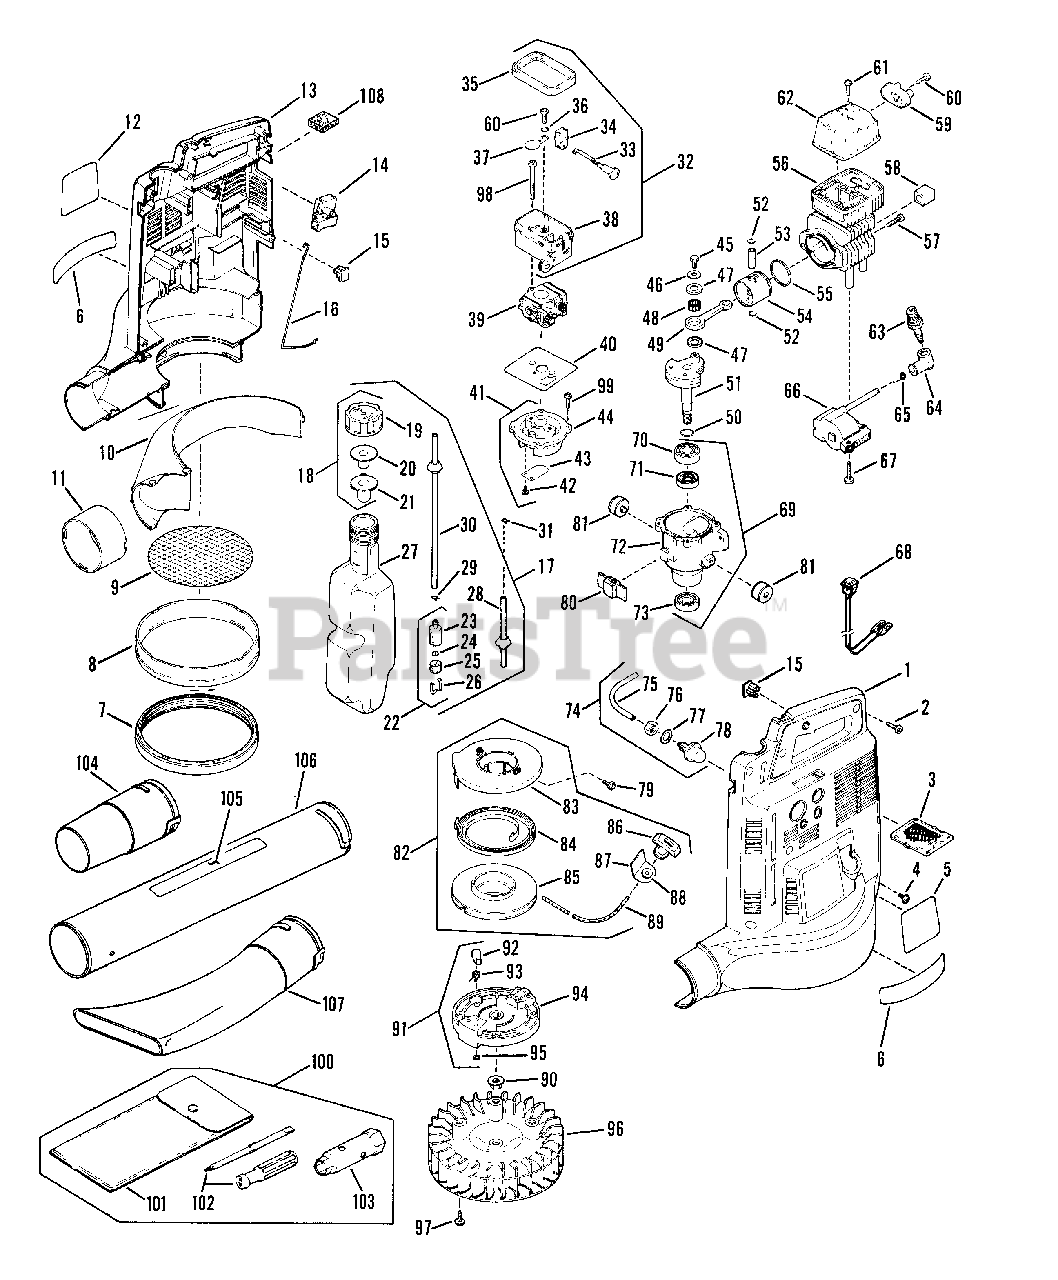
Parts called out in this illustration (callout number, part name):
1	HOUSING, Blower (L.H.)
2	SCREW, M4.5x 18mm
3	ELEMENT, Air Filter
4	SCREW, M4 x 16mm
5	DECAL, Starting Instructions
6	DECAL, Snapper
7	RING, Lower Housing
8	RING, Air Inlet
9	GUARD, Mesh
10	GUIDE, Air Flow
11	RING, Exhaust
12	DECAL, Model
13	HOUSING, Blower (R.H.)
14	ASSEMBLY, Throttle/Lockout
16	ROD, Throttle
17	ASSEMBLY, Tank
18	ASSEMBLY, Cap
19	CAP, Fuel Tank
22	ASSEMBLY, Filter
26	RETAINER
27	TANK, Fuel
28	TUBING, Overflow
30	TUBING, Filter
32	ASSEMBLY, Body
33	ROD, Choke
34	GROMMET
38	BODY
39	ASSEMBLY, Carburetor (See page 4 for breakdown)
41	ASSEMBLY, Cover
44	COVER
48	BEARING, Roller
49	ROD, Piston
51	ASSEMBLY, Crankshaft
52	RING, Clip
53	PIN, Piston
54	PISTON
55	RING, Piston
56	CYLINDER
57	SCREW, M5 x 20mm
58	MOUNT, Rear
59	TAIL, Muffler
60	SCREW, M4 x 16mm
61	SCREW, M5 x 2mm
62	MUFFLER
64	CAP, Spark Plug
66	ASSEMBLY, Coil
67	SCREW, M4x25mm
68	ASSEMBLY, Switch
69	ASSEMBLY, Crankcase
70	BEARING
72	HOUSING, Crankcase
73	BEARING
74	ASSEMBLY, Pump
75	HOSE, Primer Joint
76	NUT, Primer
78	ASSEMBLY, Primer Body
79	SCREW, M4x8mm
80	MOUNT, Front
81	MOUNT, Side
82	ASSEMBLY, Starter
83	PLATE, Starter
86	HANDLE, Rope
88	GUIDE, Rope
89	ROPE, Starter
91	ASSEMBLY, Rotor
92	RATCHET
97	SCREW, M4x20mm
98	SCREW, M5x45mm
99	SCREW, M4x16mm
100	KIT, Tool
101	BAG
102	SCREWDRIVER
103	SOCKET
104	NOZZLE, Jet Type
105	DECAL, Snapper
106	PIPE
107	NOZZLE, Fan Type
108	PRE-FILTER
